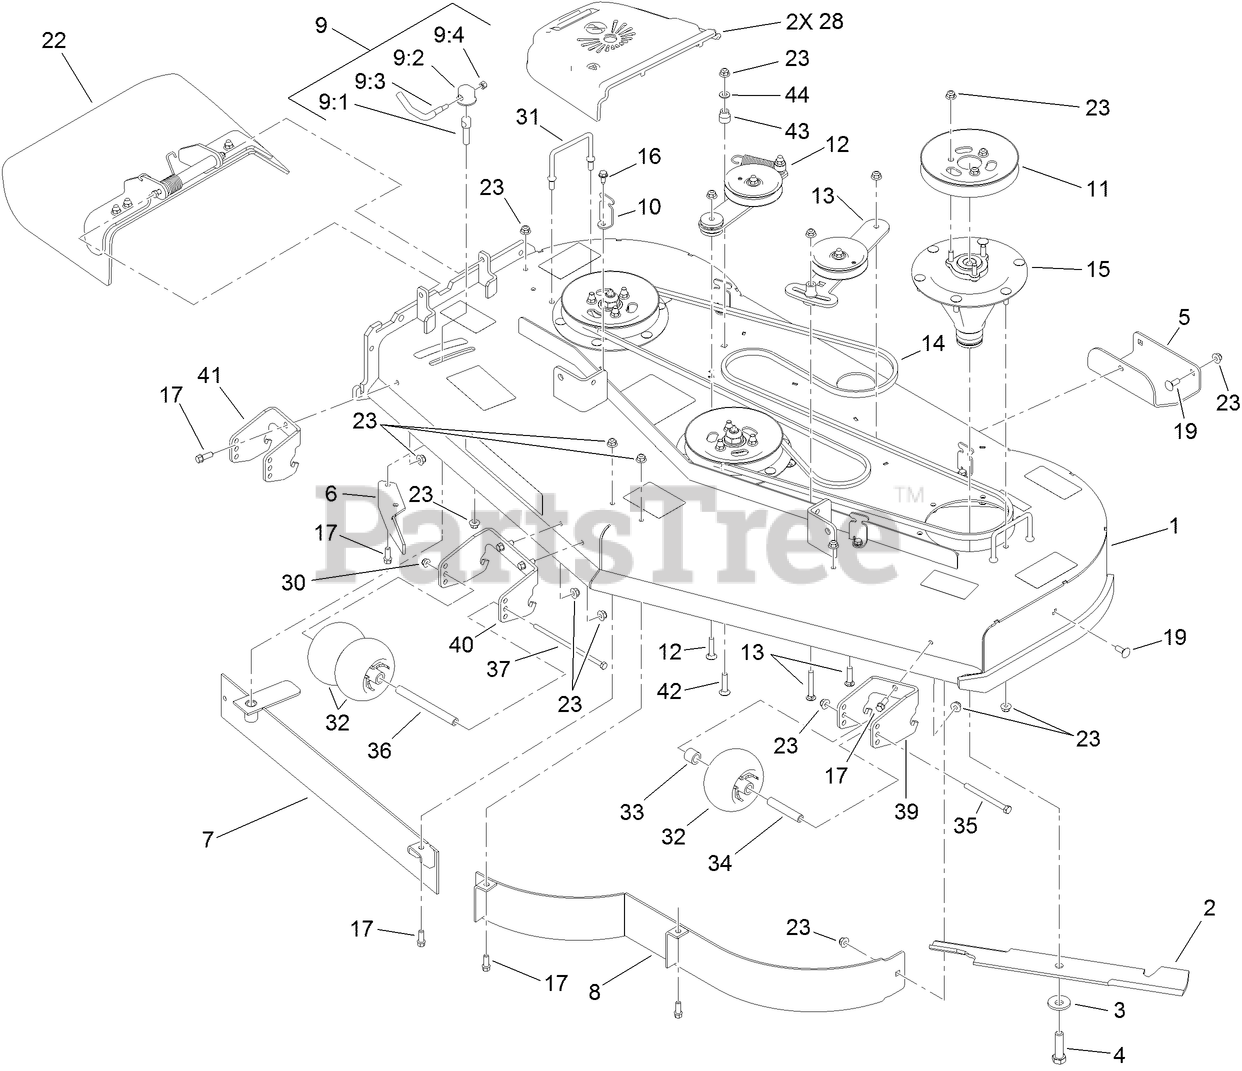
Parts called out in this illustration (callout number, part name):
1	DECK ASM
2	BLADE-HI FLOW
3	Washer-Blade Bolt, Heavy
4	SCREW-BLADE
6	BAFFLE-DISCHARGE
7	BAFFLE ASM
8	BAFFLE ASM
9	LEVER ASM
9:1	Screw-Lock
9:2	CAP-LOCK
9:3	Lever-Lock
9:4	NUT-LOCK, NI
10	BRACKET-COVER
11	PULLEY
12	IDLER ARM ASM
13	IDLER ADJUST ASM
14	BELT-V
15	SPINDLE ASM
16	SCREW-HWHTF
17	SCREW-HWH
19	BOLT-CARR
22	DEFLECTOR ASM
23	NUT-HF, NI
28	COVER-BELT
30	NUT-HF, NI
31	WIREFORM-COVER
32	ROLLER-SCALP, ANTI
33	TUBE-SPACER
34	TUBE-SPANNER
35	SCREW-HH
36	SPACER-WHEEL
37	SCREW-HH
39	BRACKET-WHEEL, LH
40	BRACKET-WHEEL, CENTER
41	BRACKET-WHEEL, RH
42	SCREW-CARR
43	BUSHING-IDLER
44	WASHER-FLAT
